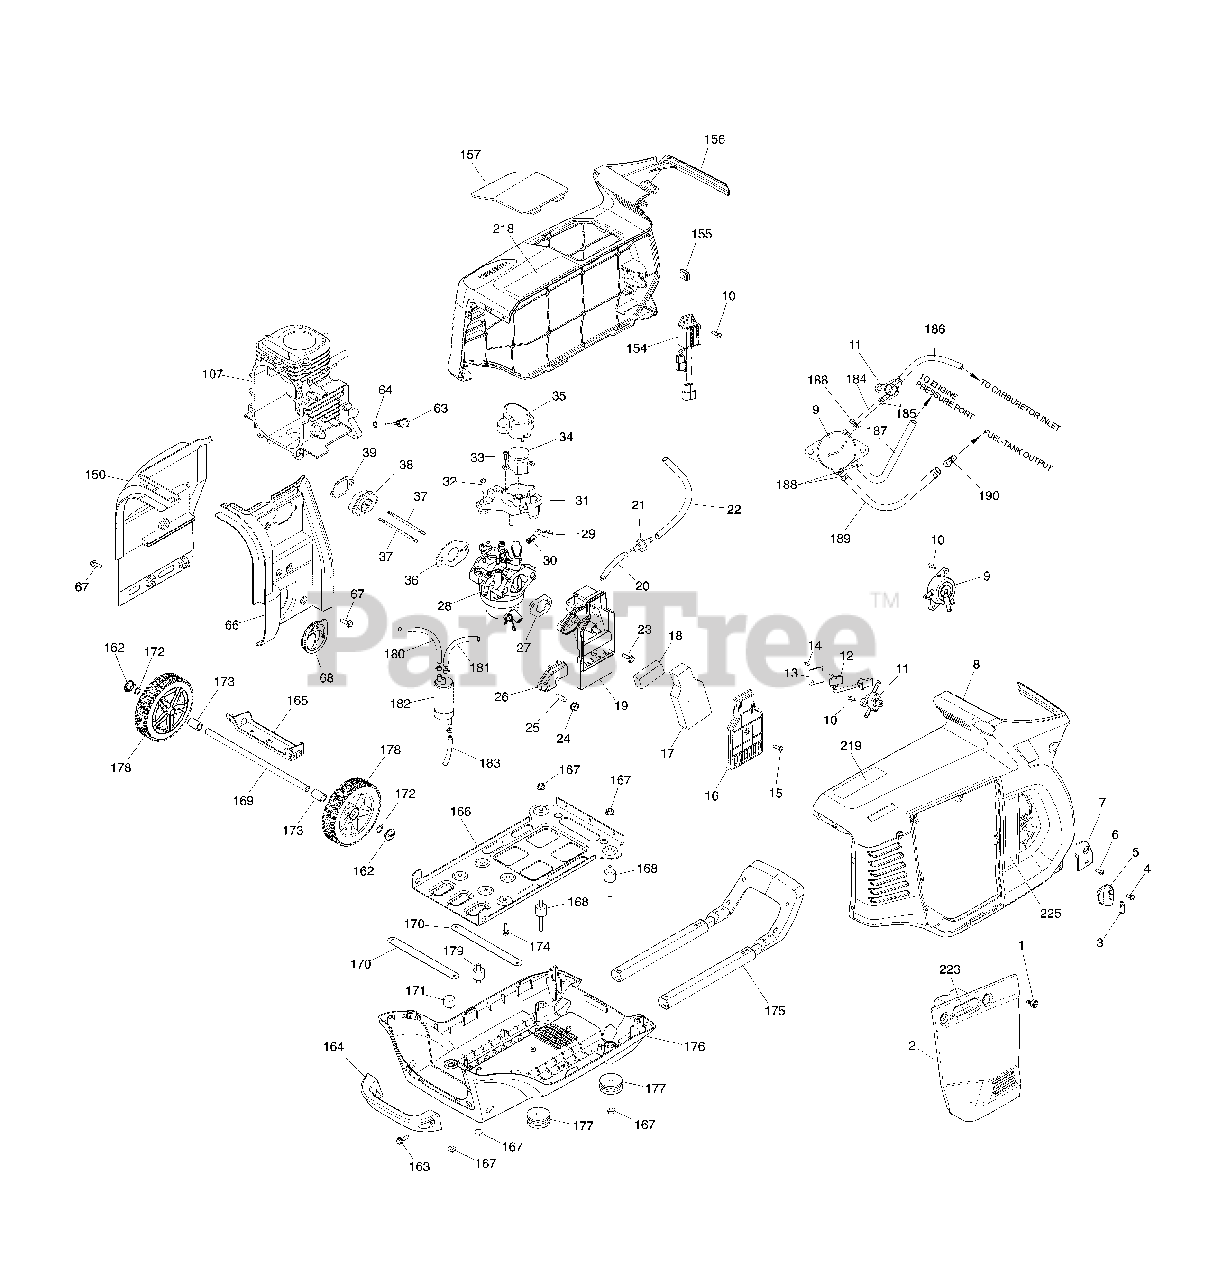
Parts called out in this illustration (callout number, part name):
4	SCREW
6	SCREW
10	SCREW
13	COVER-SWITCH
14	SCREW
16	COVER-AIR CLEANER
17	FILTER-A/C FOAM
18	FILTER-A/C FOAM
19	BASE-AIR CLEANER
23	BOLT
24	NUT
25	SLEEVE
26	COVER-AIR CLEANER
27	GASKET-AIR CLEANER
29	ROD-THROTTLE
30	SPRING
32	SCREW
33	SCREW
34	MOTOR-STEPPER
66	DEFLECTOR
67	BOLT, M6 X 12
68	SEAL-RUBBER
107	CRANKCASE
150	DEFLECTOR
154	REGULATOR-VOLTAGE
155	NUT
157	COVER-SPARK PLUG
163	BOLT, M6 X 25
168	MOUNT-VIBRATION
171	MOUNT-VIBRATION
172	CLIP
174	BOLT, M8 X 16
177	MOUNT-VIBRATION
179	MOUNT-VIBRATION
185	CLAMP
188	CLAMP
